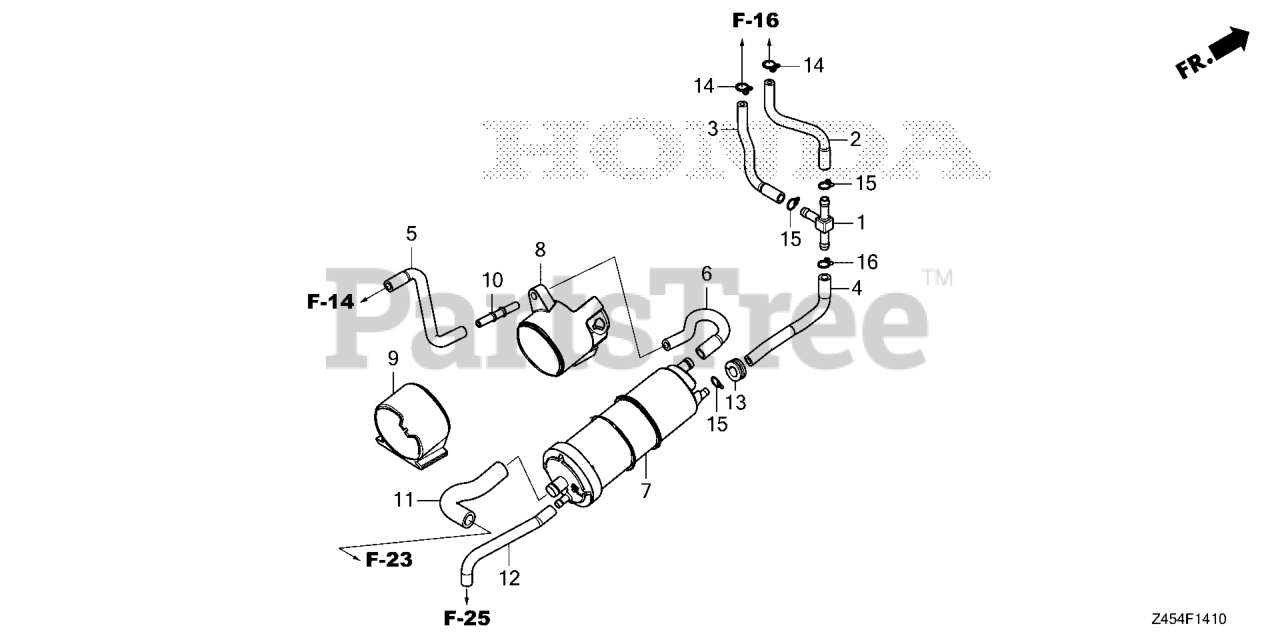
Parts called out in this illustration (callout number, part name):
1	PIPE, THREE WAY JOINT
7	CANISTER COMP
8	RUBBER A, CANISTER
9	RUBBER B, CANISTER
10	JOINT, TUBE
11	TUBE, CANISTER AIR
12	TUBE, CANISTER DRAIN
13	RUBBER, TUBE MOUNT
14	CLIP, TUBE (B7)
15	CLIP, TUBE (B8)
16	CLIP, TUBE (C9)
